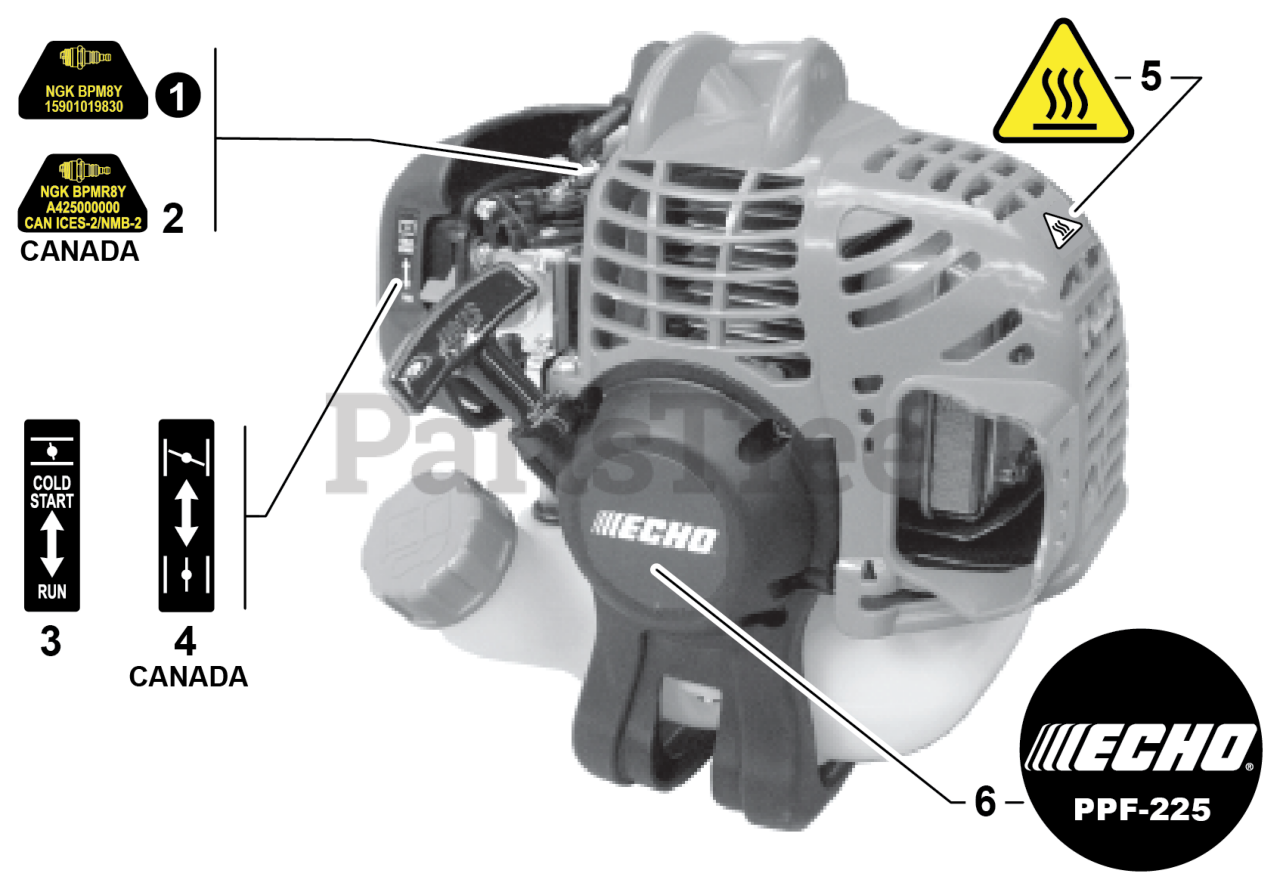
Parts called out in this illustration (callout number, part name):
1	LABEL - SPARK PLUG - BPM8Y
2	LABEL - SPARK PLUG - BPMR8Y
3	LABEL - CHOKE
4	LABEL - CHOKE
5	LABEL - CAUTION - HOT
6	LABEL - STARTER - PPF-225
